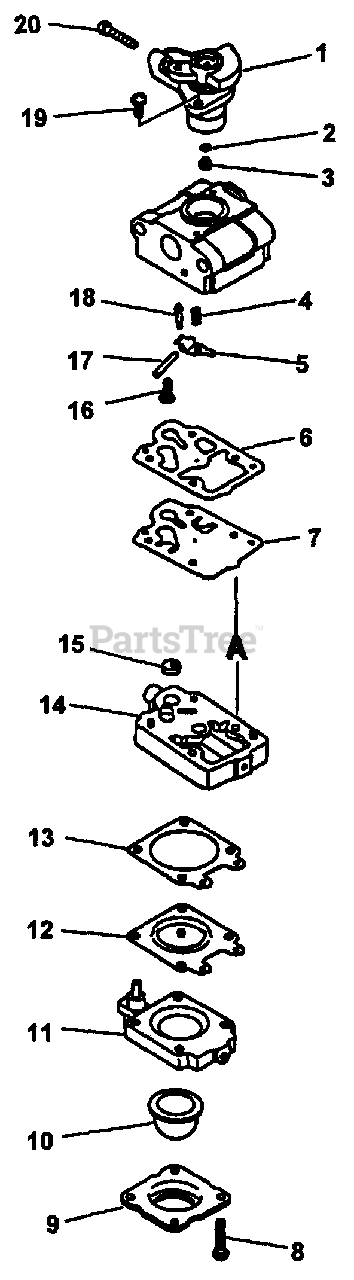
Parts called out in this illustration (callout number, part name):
1	VALVE, THROTTLE
2	O-RING
3	JET - 38
4	SPRING, METERING LEVER
5	LEVER, METERING
6	GASKET, PURGE
7	DIAPHRAGM, PURGE
8	SCREW, PUMP COVER
9	RETAINER, PURGE BULB
10	BULB, PURGE
11	PURGE BASE ASSY
12	DIAPHRAGM, METERING
13	GASKET, METERING
14	BASE, PURGE
15	STRAINER
16	SCREW, METERING LEVER PIN
17	PIN, METERING LEVER
18	VALVE, INLET
20	SCREW, IDLE ADJUST
